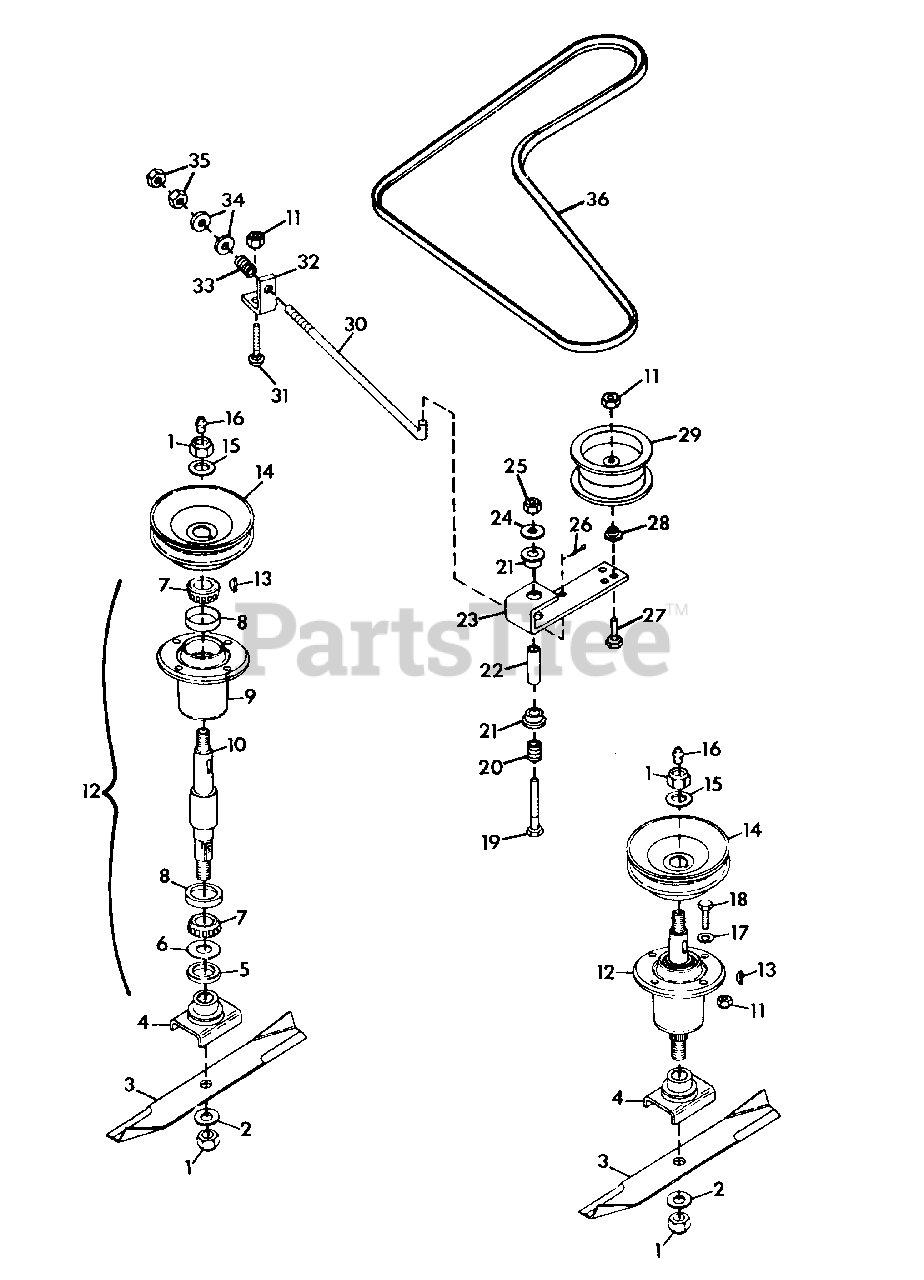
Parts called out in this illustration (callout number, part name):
1	NUT, LOCK 5/8-11
2	WASHER, FLAT .656X1.312X.095
3	BLADE
4	CRADLE, BLADE
5	SEAL, STEEL
6	WASHER, FLAT .975X1.970X.030
7	CONE, ROLLER BEARING
8	CUP, ROLLER BEARING
9	HOUSING, BEARING
10	SHAFT, SPINDLE
11	NUT, LOCK 3/8-16
12	ASSEMBLY, SPINDLE
13	KEY, WOODRUFF 1/4X1 HARD
14	SHEAVE, SPINDLE
15	WASHER, FLAT .687X1.312X.130
16	FITTING, LUBE 1/8 NPT
17	WASHER, FLAT .438X1.00X.800
18	BOLT, HEX 3/8-16X1.250
19	BOLT, HEX 1/2-13X3.25
20	SPRING, COMPRESSION 1X.80X36 LB/N
21	BUSHING, NYLON .760X1.00X.600
22	SPACER
23	ARM, IDLER PIVOT
24	WASHER, FLAT .531X1.250X.100
25	NUT, LOCK 1/2-13
26	PIN, COTTER .09X.62
27	BOLT, HEX 3/8-16X2.25
28	BUSHING
29	PULLEY, IDLER
30	ROD, IDLER
31	BOLT, 3/8-16X1.00 RD HD SQ NK
32	BRACKET, BELT TENSIONER
33	SPRING, COMPRESSION 1.00X.78
34	WASHER, FLAT .406X.812X.065
35	NUT, HEX 3/8-24
36	BELT, V-DRIVE
